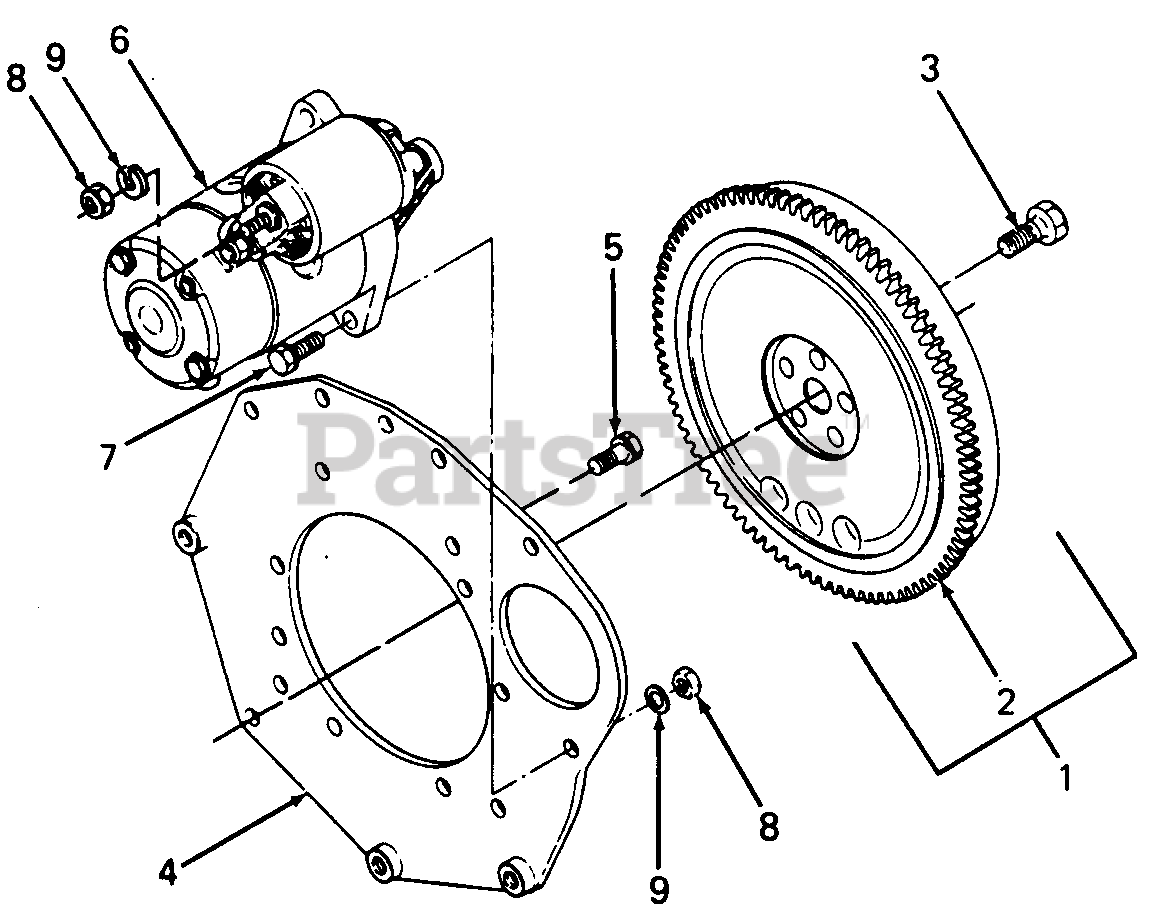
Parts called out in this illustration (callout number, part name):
1	Flywheel Assy
3	Bolt, Flywheel
4	Plate, Rear End
5	Screw, Hex Cap w/Washer
6	Starter
7	Screw, Hex Cap w/Washer
9	Washer, Lock
